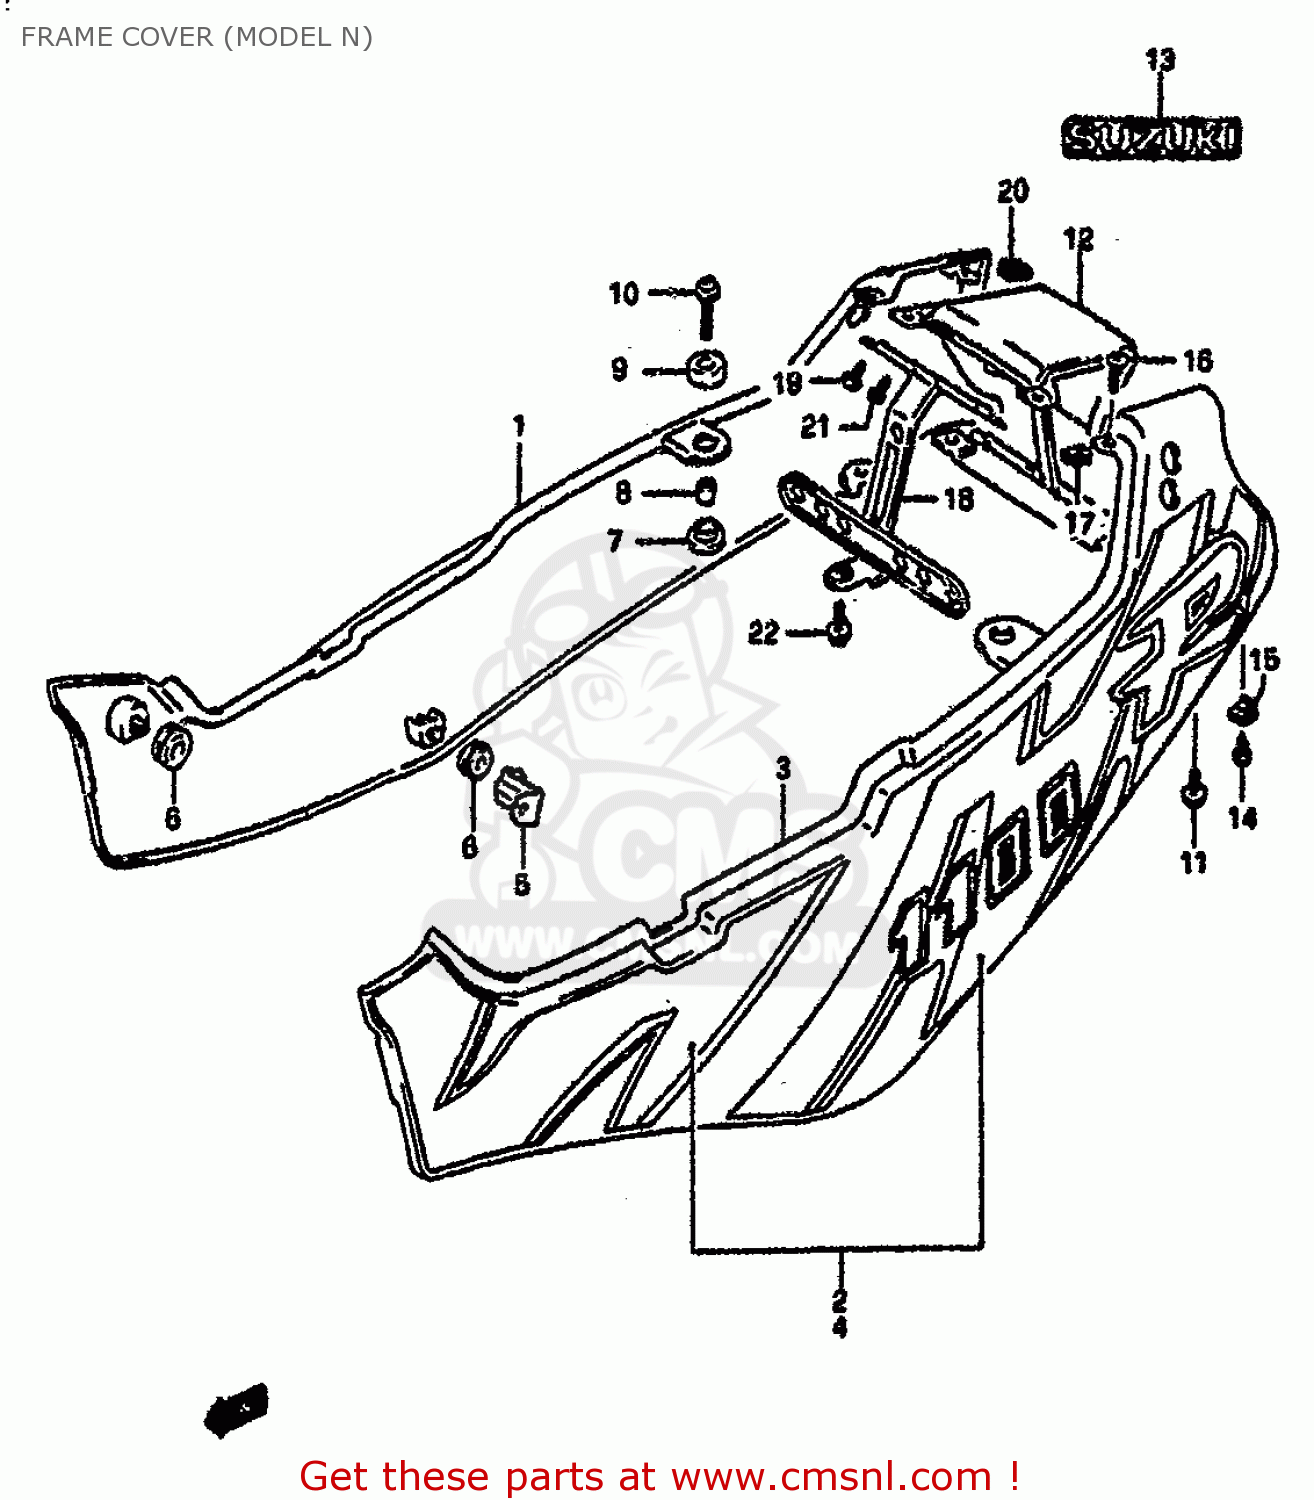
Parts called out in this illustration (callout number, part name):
1	COVER,FRAME,R(WHITE)
2	TAPE SET,FRAME COVER,RIGHT
3	COVER,FRAME,L(WHITE)
4	TAPE SET,FRAME COVER,L
5	BRACKET,FRAME COVER
6	CUSHION
7	CUSHION,FRAME COVER LWR
8	SPACER
9	CUSHION,TAIL COVER UPR
10	SCREW(6X30)
11	SCREW (6X16)
12	COVER,FRAME CTR
13	EMBLEM
14	SCREW
15	NUT
16	SCREW, BRACKET
17	NUT
18	BRACKET,TAIL LAMP
19	SCREW, BRACKET
20	NUT
21	SCREW
22	BOLT
26	COVER,FRAME CTR
27	EMBLEM
28	SCREW
29	NUT
30	SCREW, BRACKET
31	NUT
32	BRACKET,TAIL LAMP
33	SCREW, BRACKET
34	NUT
35	SCREW
36	BOLT
